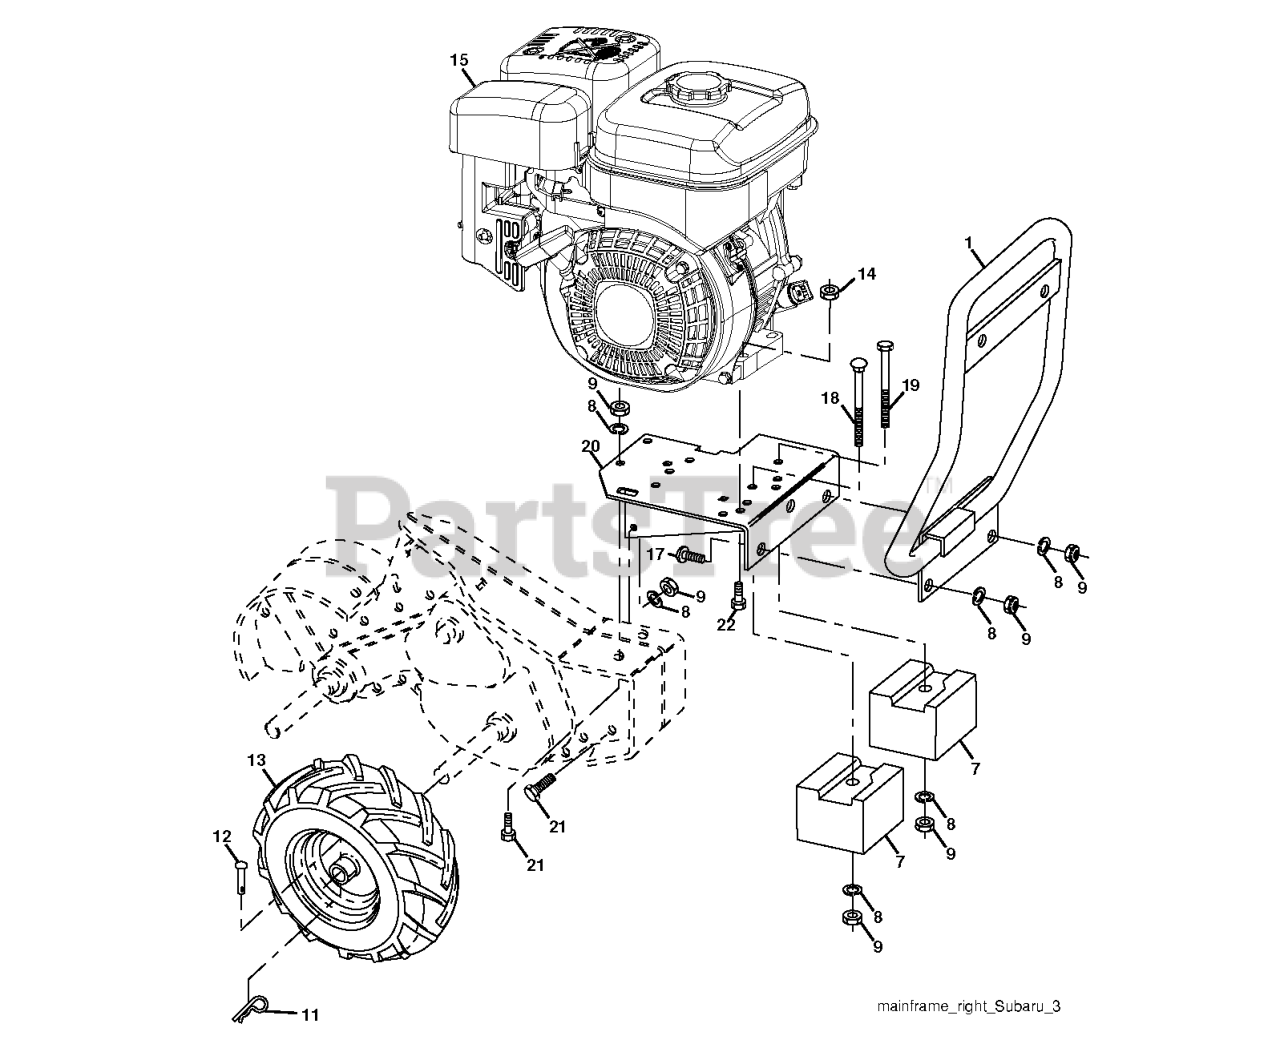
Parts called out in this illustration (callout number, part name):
1	BUMPER
7	COUNTERWEIGHT
8	WASHER, LOCK 3/8
9	NUT.HEX.3/8-16UNC
11	SPRING TI
13	WHEEL.DR.RH.16X4X8.TILLER.SILV
14	LOCKNUT-FLANGE 5/16-18
17	BOLT D
18	Bolt, Carriage 3/8-16 x 4-1/2
19	BOLT, HEX 3/8-16X4-1/2
20	BASE.ASM.ENGINE.SUBARU.7HP.BLA
21	BOLT
22	BOLT, HEX 5/16-18X1-3/4
